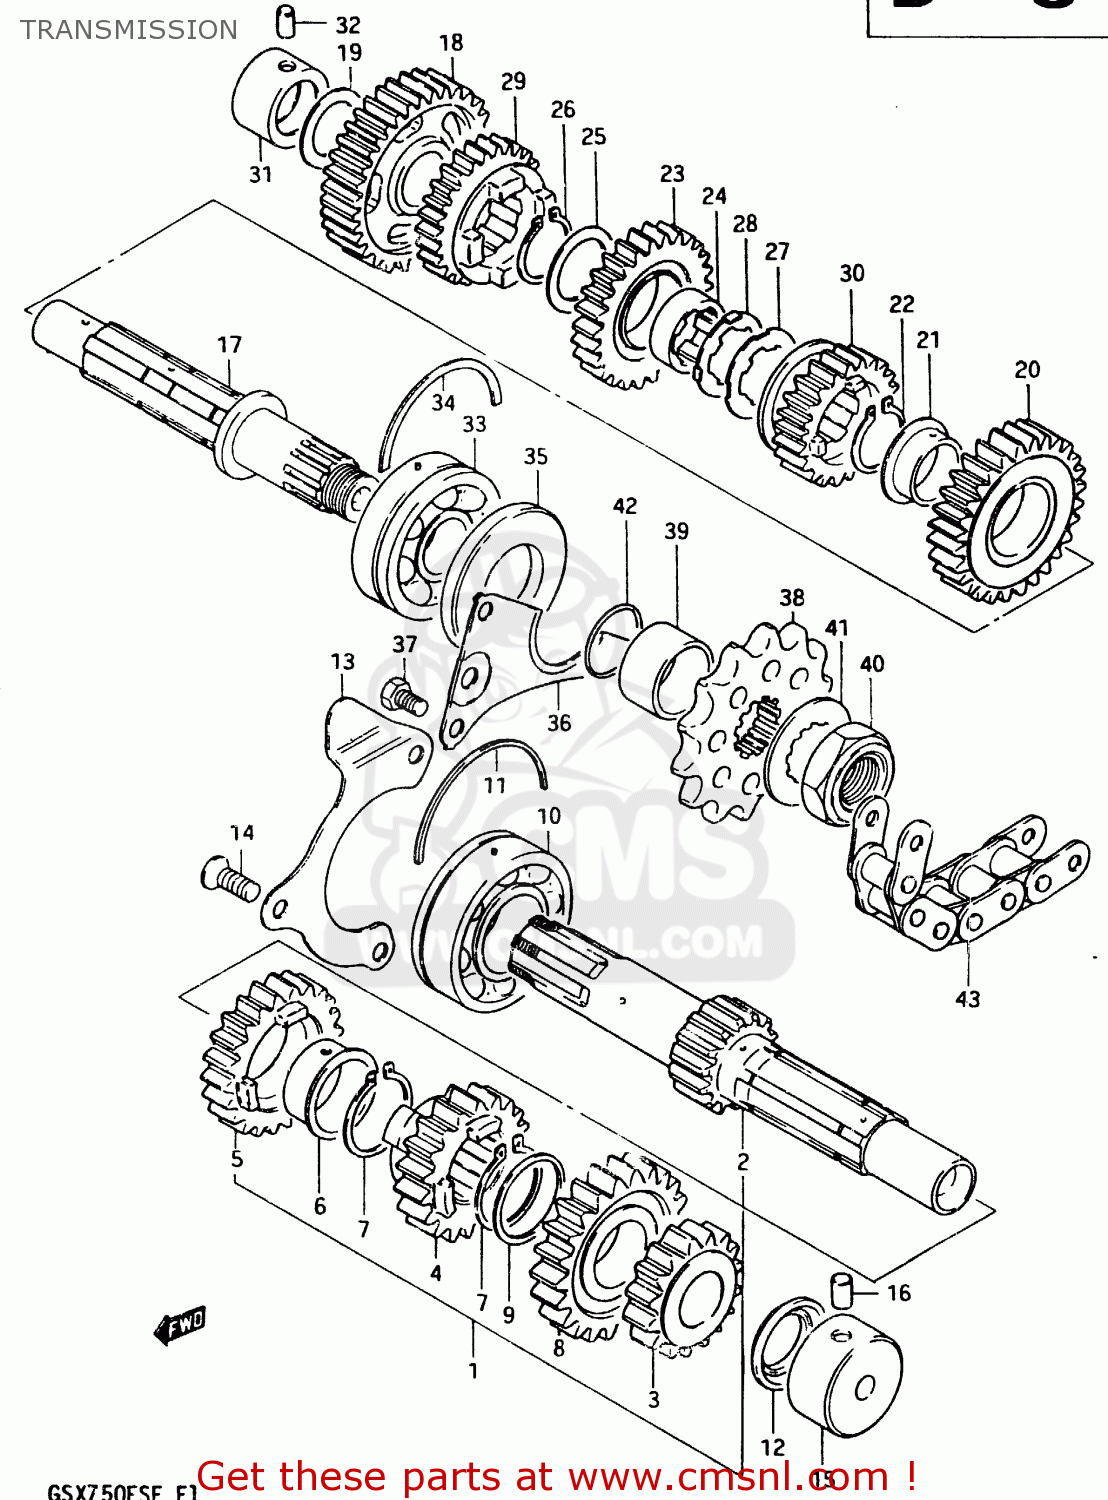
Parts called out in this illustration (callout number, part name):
1	SHAFT,COUNTER
2	SHAFT,COUNTER
3	GEAR,SECOND DRIVE
4	GEAR,THIRD DRIVE
5	GEAR,FOURTH DRIVE
6	BUSHING
7	RING,SNAP
8	GEAR,FIFTH DRIVE (NT:23)
9	WASHER,LOCK
10	BEARING(25X62X17)
11	C-RING
12	SEAL,OIL(20X31.2X2.7)
13	PLATE,COUNTERSHAFT BEARING
14	SCREW
15	BEARING(20X34X17.5)
16	PIN
17	SHAFT,DRIVE
18	GEAR,1ST DRIVEN(NT:35)
19	WASHER
20	GEAR,2ND DRIVEN(NT:28)
21	BUSH(28X32X2)
22	CIRCLIP
23	GEAR,THIRD DRIVEN
24	BUSH,3RD DRIVEN GEAR
25	WASHER,LOCK
26	CIRCLIP
27	WASHER,LOCK
28	WASHER
29	GEAR,FOURTH DRIVEN
30	GEAR,5TH DRIVEN(NT:22)
31	BEARING(20X34X20)
32	PIN
33	BALL BEARING 25X62X17
34	C-RING
35	SEAL,OIL(33X62X7)
36	PLATE,DRIVESHAFT OIL
37	BOLT
38	SPROCKET,ENGINE
39	SPACER (25X33X20.1)
40	NUT
41	WASHER
42	O RING(D:1,ID:24.5)
43	CHAIN ASSEMBLY,DRIVE
